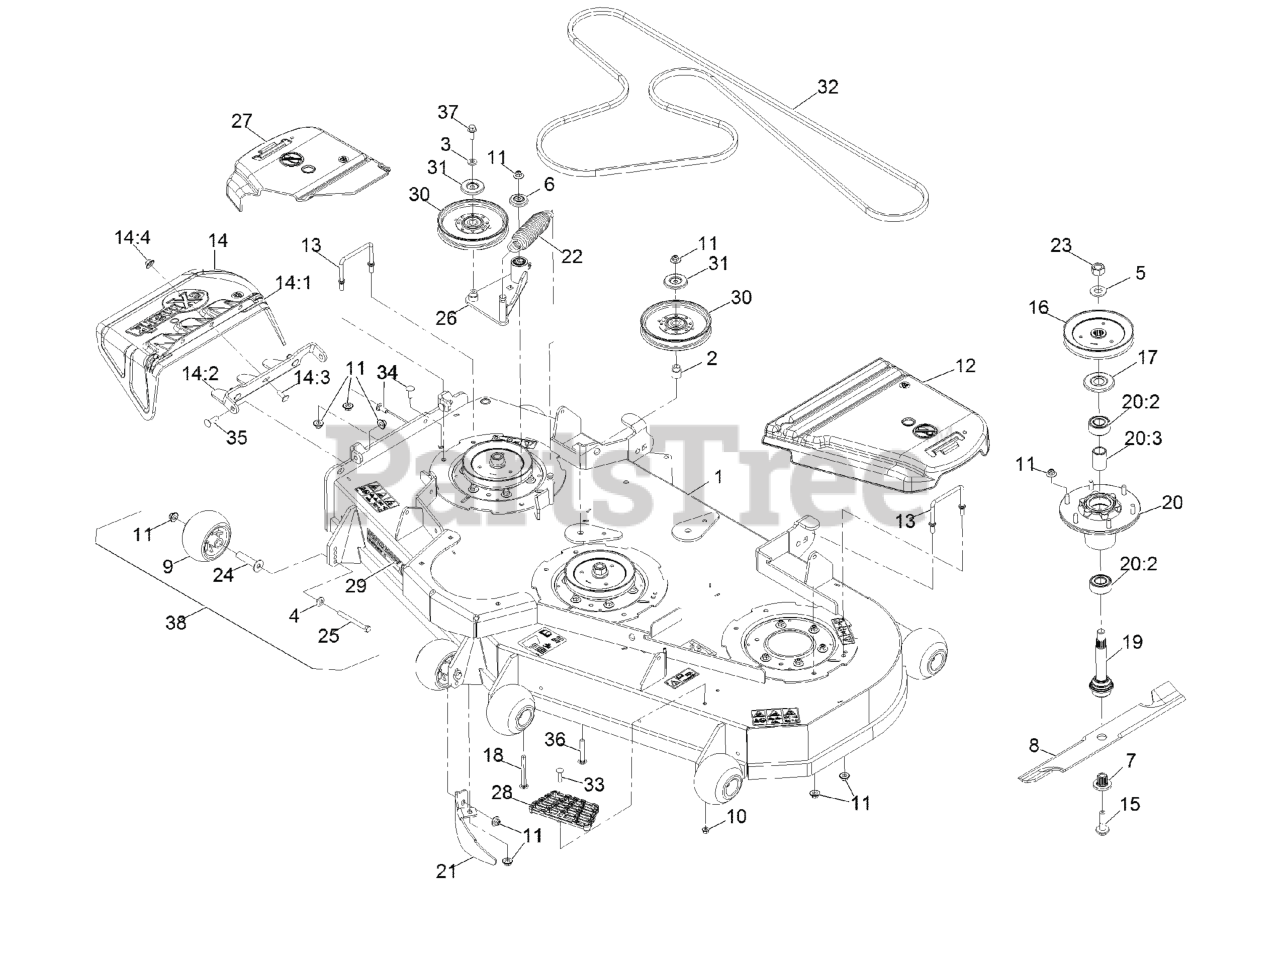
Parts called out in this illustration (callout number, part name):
1	Deck ASM, W/Decals 60
2	BUSHING-IDLER
4	WASHER-BELLEVILLE
6	GUARD-TOP
7	BUSHING,SPLINED
8	Blade-Extreme 2, 20.50"
9	ROLLER-SCALP, ANTI
10	NUT-HF, NI
11	Nut-Nyloc 3/8-16 Flg
12	COVER-BELT, LH
13	WIREFORM-COVER
14	ASM,DISCHARGE CHUTE
14:1	CHUTE,DISCHARGE
14:2	BRACKET,DISCHARGE CHUTE
14:3	SCREW-CARR
14:4	Nut-Nyloc 3/8-16 Flg
15	SCREW,SEMS 1/2-20 X 2.19
16	SHEAVE,BLADE DRIVE 6.50
17	GUARD-BEARING, TOP
18	BOLT-SHOULDER, CARRIAGE 3/8-16 X 3 1/2
19	ASM-SPINDLE AND SEAL
20	ASM-Cutter Hsg
20:2	Bearing-3205 Trashguard
20:3	Spacer-Bearing
21	DOGLEG - LZ60
22	SPRING-EXTENSION
23	NUT-HEX
24	AXLE, ROLLER
25	SCREW-HH 3/8-16 X 3 3/4 GR 8
26	IDLER ARM ASM
27	BELTSHIELD-RT, 60
28	STEP-DECK
29	DECAL, 604
30	IDLER-PULLEY
31	SHIELD-DUST
33	Bolt-Carriage 5/16-18 X 1 1/4
34	SCREW-CARR
35	Bolt-Carriage 3/8-16 X 1 1/4
36	SCREW-CARR
37	SCREW-HHF
38	KIT, ANTI-SCALP ROLLER
